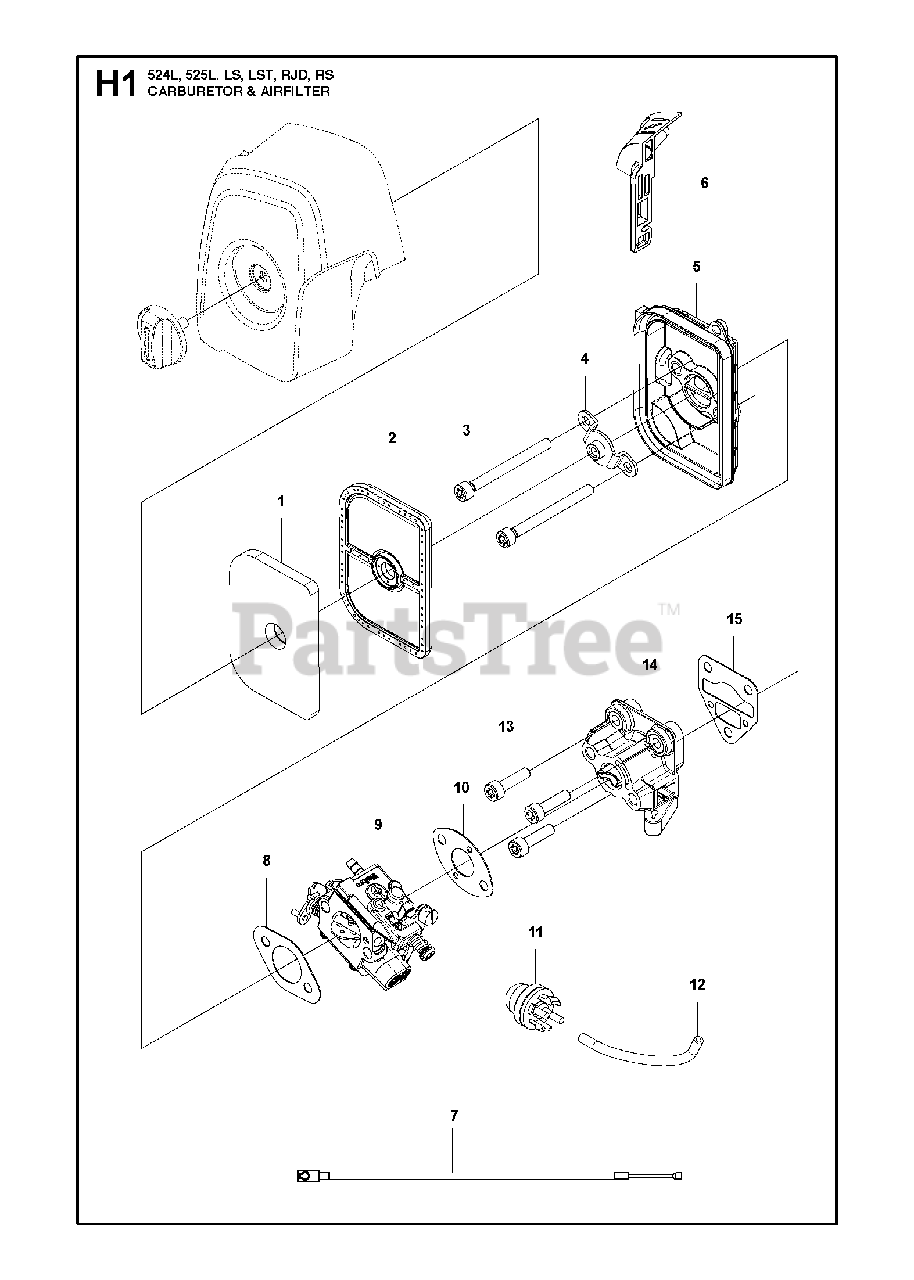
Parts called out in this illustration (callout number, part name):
1	AIR FILTER
5	FILTER HOUSING
6	CHOKE CONTROL
7	THROTTLE CABLE
9	CARBURETTOR ASSY
10	GASKET CARBURETOR
11	AIR PURGE BUBBLE
13	BOLT
